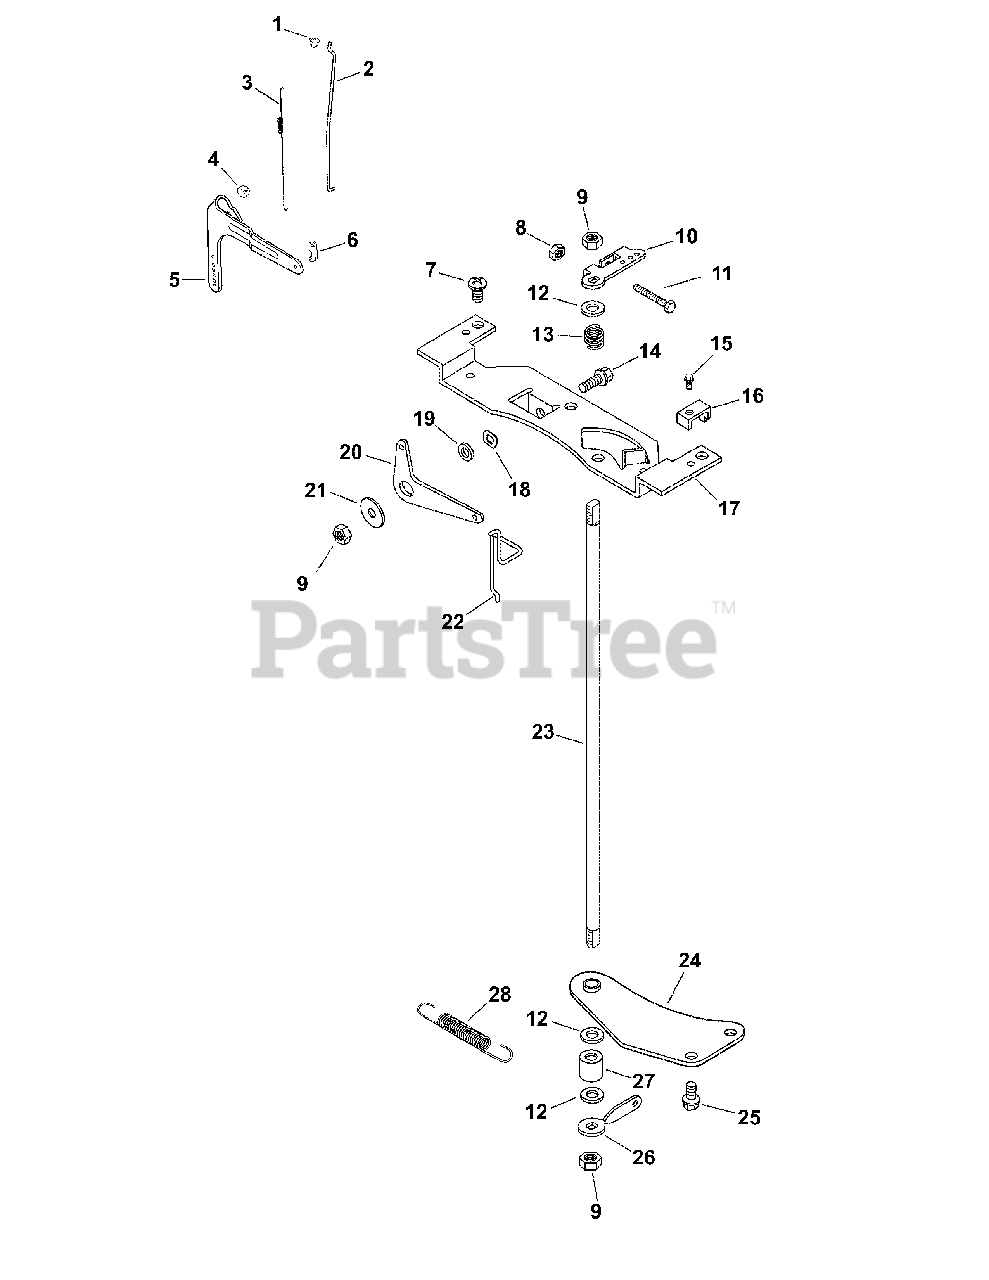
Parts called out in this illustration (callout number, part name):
1	Bushing, Lingage Retaining
2	Linkage, Throttle
3	Spring, Linkage
4	Nut, FLG M6 x 1.0
5	Lever, Governor
6	Bushing, Throttle Linkage
7	Screw, Phl Hd 11-16 x 3/4"
8	Nut, M4 x 0.7
9	Nut, Lock M6 x 1.0
10	Lever, Throttle Control
11	Screw, Cap M4 x 0.7 x 30
12	Washer, Flat 1/4"
13	Spring, Throttle Shaft
14	Screw, Flg M6x1.0x16
15	Screw, Flg Thd Frm M5 x 0.8 x 16
16	Clamp, Cable
17	Bracket, Control
18	Washer, Spring 3/8"
20	Lever, Choke
21	Washer, Flat 1/4"
22	Linkage, Choke
23	Shaft, Throttle
24	Bracket, Throttle Shaft
25	Screw, Flg Thd Frm M6 x 1.0 x16
26	Lever, Throttle Control
28	Spring, Governor
